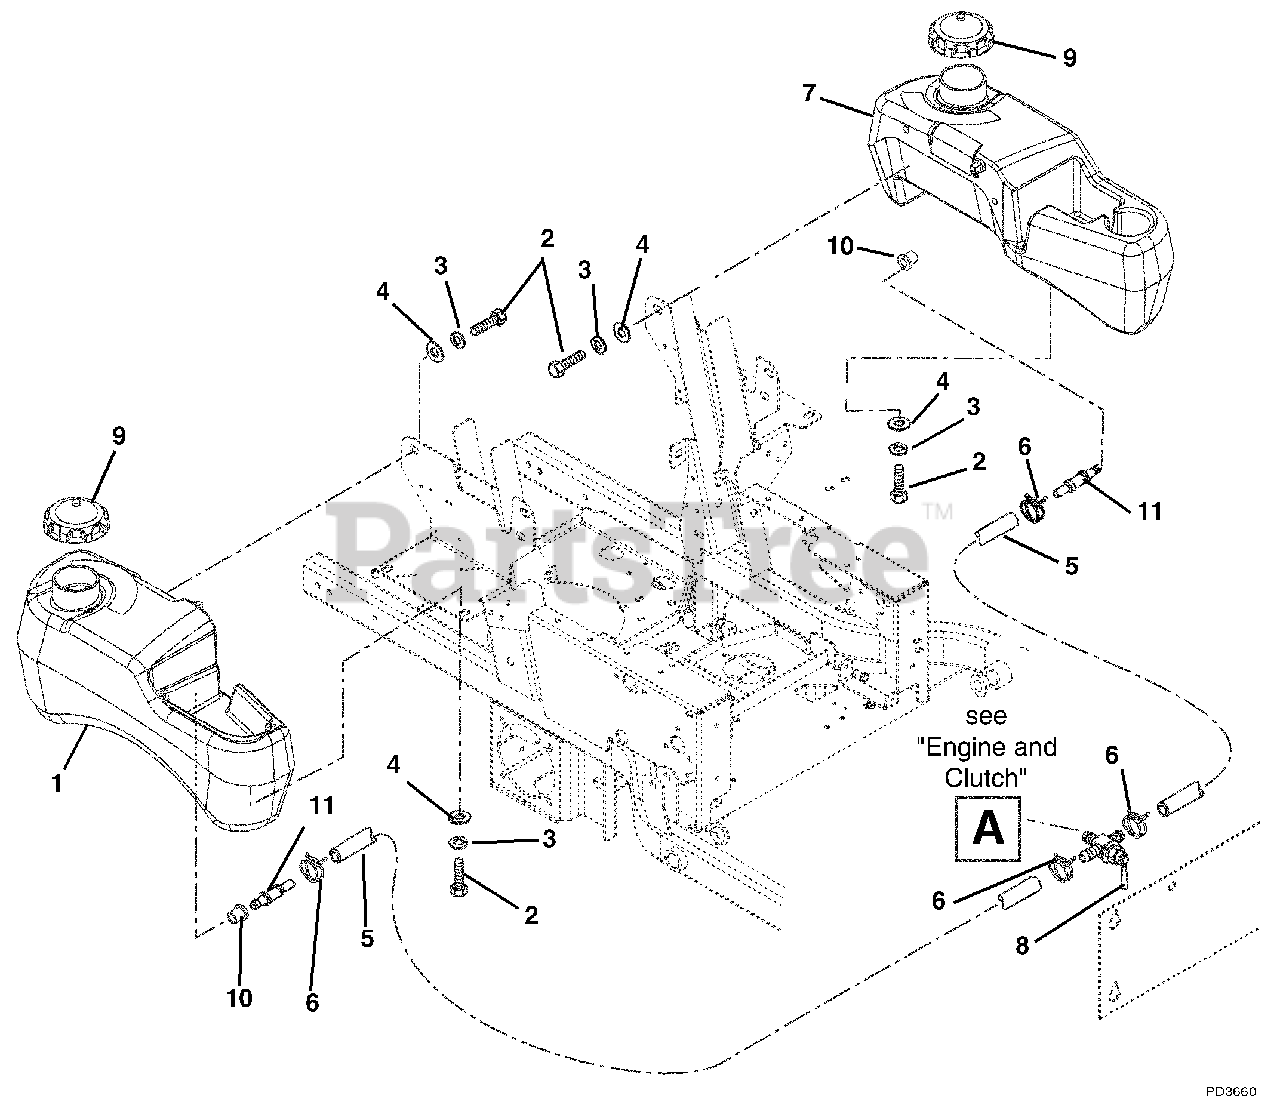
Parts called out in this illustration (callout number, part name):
1	Tank, Gas- Right Hand
2	Bolt-Hex .31-18 x .75 Grade 5
3	Washer-Locking .31 x .078
4	Washer-Flat-Steel .38 x .875 x .083
5	Gas Line-Bulk 1/4" ID
6	Hose-Clamp
7	Tank, Gas- Left Hand
8	Valve, Fuel
9	Cap-Gas
10	Bushing
11	Fuel Tank Fitting
